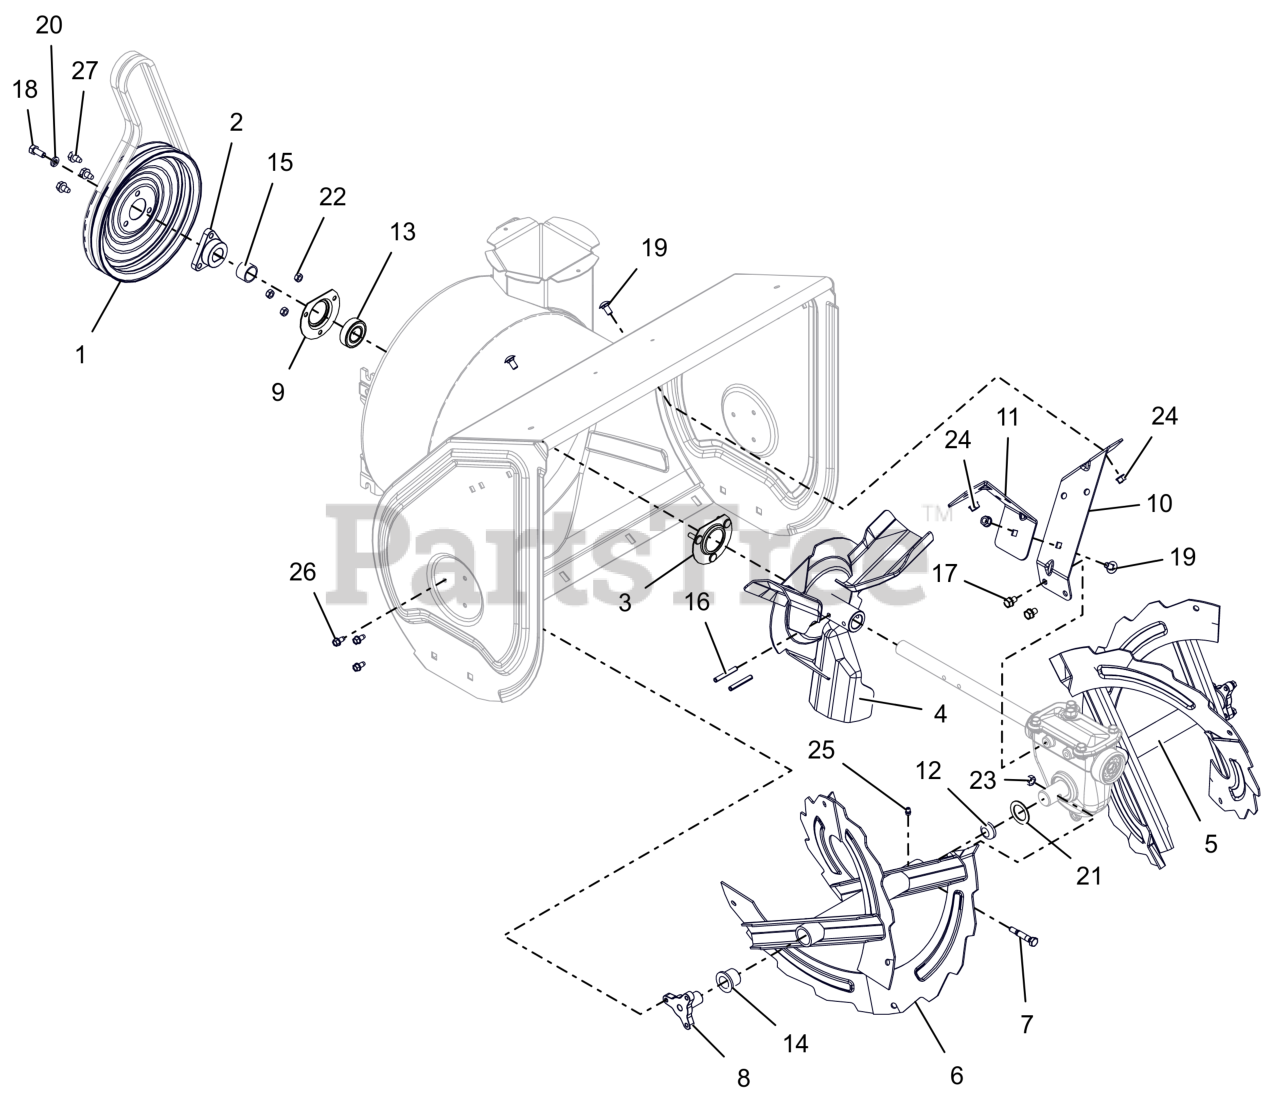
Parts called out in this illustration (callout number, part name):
1	PULLEY, SPIN FORM DUAL GROOVE
2	PULLEY HUB, D-BORE .87 PRO
3	BEARING FLANGE
4	IMPELLER, 3 BLADE-14"
5	RAKE, LH W/ZERK - 24"
6	RAKE, RH W/ZERK - 24"
7	SHEAR BOLT SERVICE ASSEMBLY
8	SUPPORT, RAKE BUSHING
9	BEARING FLANGE
10	BRACKET, GEARCASE SUPPORT - LH
11	BRACKET, GEARCASE SUPPORT - RH
12	PLUG, RAKE TUBE
13	BRG-BALL .876 X 1.750 X .50
14	BSHG-FLG, NY.778 ID X 1.018 OD
15	BSHG,SPCR .895X1.065X.693
16	PIN-ROLL .250X1.75
17	BLT, SEMS .31-18X.50 G5 ZCC
18	BLT, HEX .31-24X.750 G5 ZCC
19	BLT,RHSSN.31-18X.625 G5 ZCCP30
20	WSHR, LK-HVY .312X.097 ZCC
21	WSHR, FLT 1.010X1.505X.062 ZCC
22	NUT,LK-CTR .25-20 GA ZCC
23	NUT,LK-CTR .31-18 GA ZCC
24	NUT-LK-TOP-FLG .312-18 GF ZCC
25	ZERK,FITTING .25X.125 DRIVE IN
26	SCR-TAP .25-20X.50 HWH ZCC
27	SCR,TAP .312-18X.50 HWH TR ZCC
